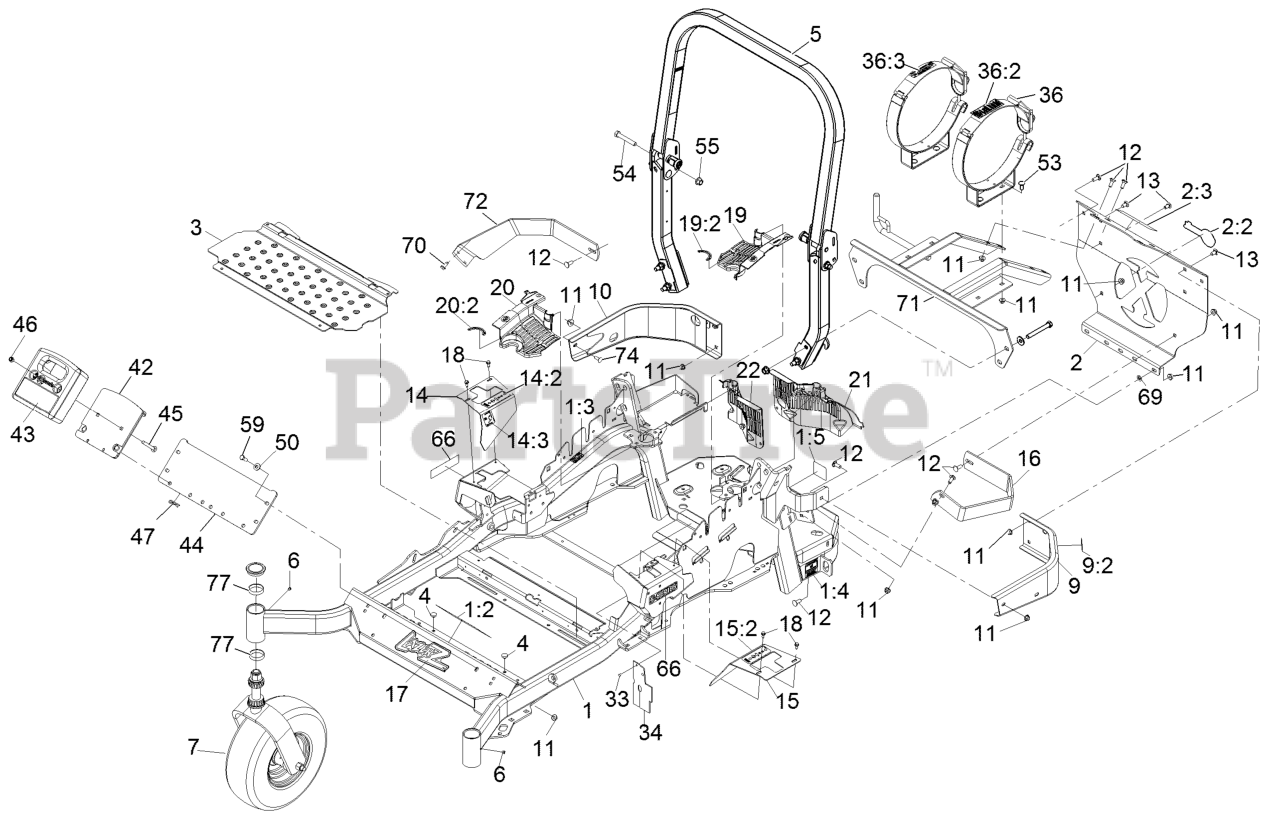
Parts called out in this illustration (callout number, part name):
1	MAINFRAME ASM
1:2	DECAL-CAUTION
1:3	DECAL-SLOPE
1:4	DECAL-BELT DRIVE
1:5	DECAL-SPARK ARRESTER
2	REAR GUARD-LP W/DECALS
2:3	DECAL-TANK REPLACEMENT
5	ROPS ASM
7	Caster Wheel Asm
9	LH BUMPER ASM
9:2	DECAL-CAUTION
10	BUMPER-RH
11	NUT-HF, NI
12	SCREW-CARR
13	SCREW-CARR
14	RH MOTION CONTROL COVER ASM
14:2	DECAL-MOTION CONTROL
14:3	DECAL-PARK BRAKE
15	LH MOTION CONTROL COVER ASM
15:2	DECAL-MOTION CONTROL
16	GUARD-MUFFLER
17	DECAL,LAZER MODEL
18	SCREW-HWH
19	LH HYDRO GUARD ASM
19:2	DECAL-HYDRO OIL
20	RH HYDRO GUARD ASM
20:2	DECAL-HYDRO OIL
21	GUARD-HYDRO, REAR (LH)
22	GUARD-HYDRO, REAR (RH)
33	RIVET-POP
34	DEFLECTOR-AIR FLOW
36	TANK BRACKET ASM (SET)
36:2	DECAL-LPG WARNING
36:3	DECAL-LPG 43.5LB TANK
42	WLD,WEIGHT MOUNT
43	WEIGHT,CAST 36LB
44	PLATE,WEIGHT ASM MOUNT
45	SCREW-CARR
46	NUT-LOCK, NI
47	PIN-HAIR
50	WASHER-BELLEVILLE
53	BOLT-CARR
54	SCREW-HH
55	Nut-Lock 1/2-13
59	SCREW-HH
66	DECAL-S-SERIES
69	NUT-PUSH
70	Screw-HWH 5/16-18 X 3/4 Tf
71	SUPPORT-TANK
72	STRAP-GUARD
74	BOLT-CARR
77	CUP-BEARING
